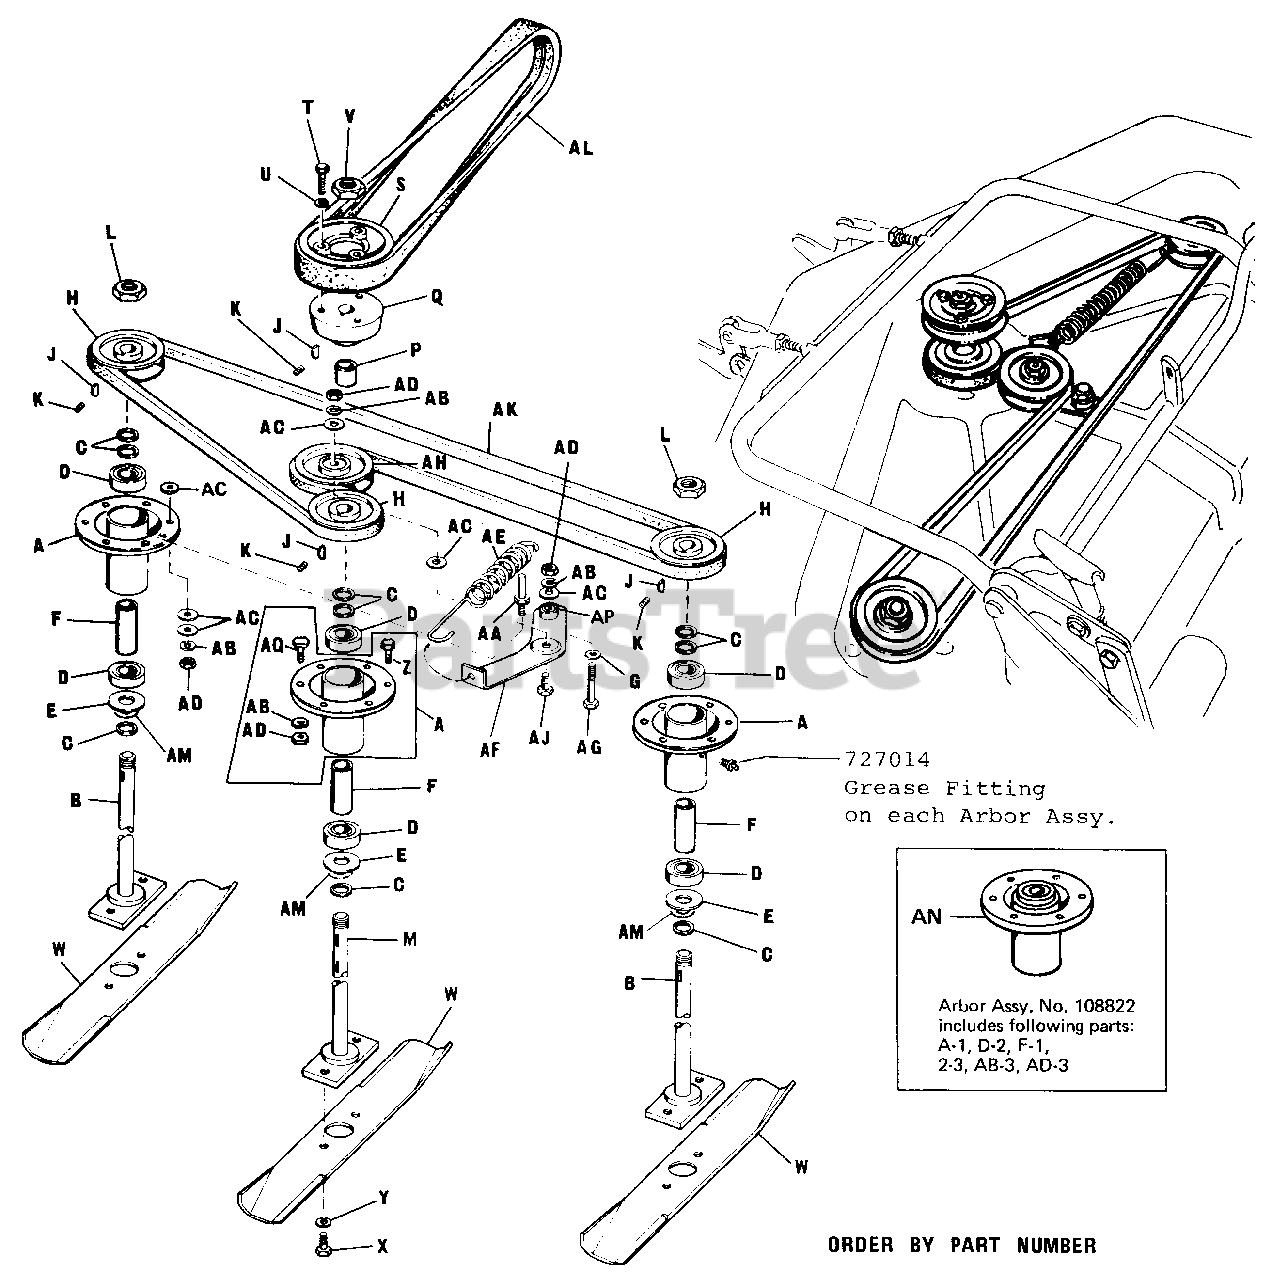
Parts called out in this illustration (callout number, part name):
A	Tube Assembly, Arbor
B	Arbor Assembly
G	Washer, Plain, 3/8"
J	Woodruff Key, #61-3/16" x 5/8" Dia.
K	Set Screw, 5/16"-18 x 3/8"
L	Hex. Lock Nut, 3/4"-16
M	Arbor Drive Assembly
T	Hex. Cap Screw, 5/16-18 x 1-1/2"
U	Lock Washer, 5/16"
V	Hex. Lock Nut, 3/4"-16
W	Knife Blade
X	Hex. Cap Screw, 3/8"-16 x 5/8"
Y	Lock Washer, 3/8"
Z	Screw Hex. Cap, 3/8"-16 NC x 3/4" lg.
AB	Lock Washer, 3/8"
AC	Plain Washer, 5/16"
AD	Full Hex Nut, 3/8"-16
AE	Tension Spring
AF	Idler Lever Assembly
AG	Hex. Cap Screw, 3/8"-16 x 1-3/4"
AH	Idler Pulley
AL	V-BELT, 45"
AN	Arbor Assembly with Bearings and Hardware
AQ	Spec. Hex. Cap Screw,
